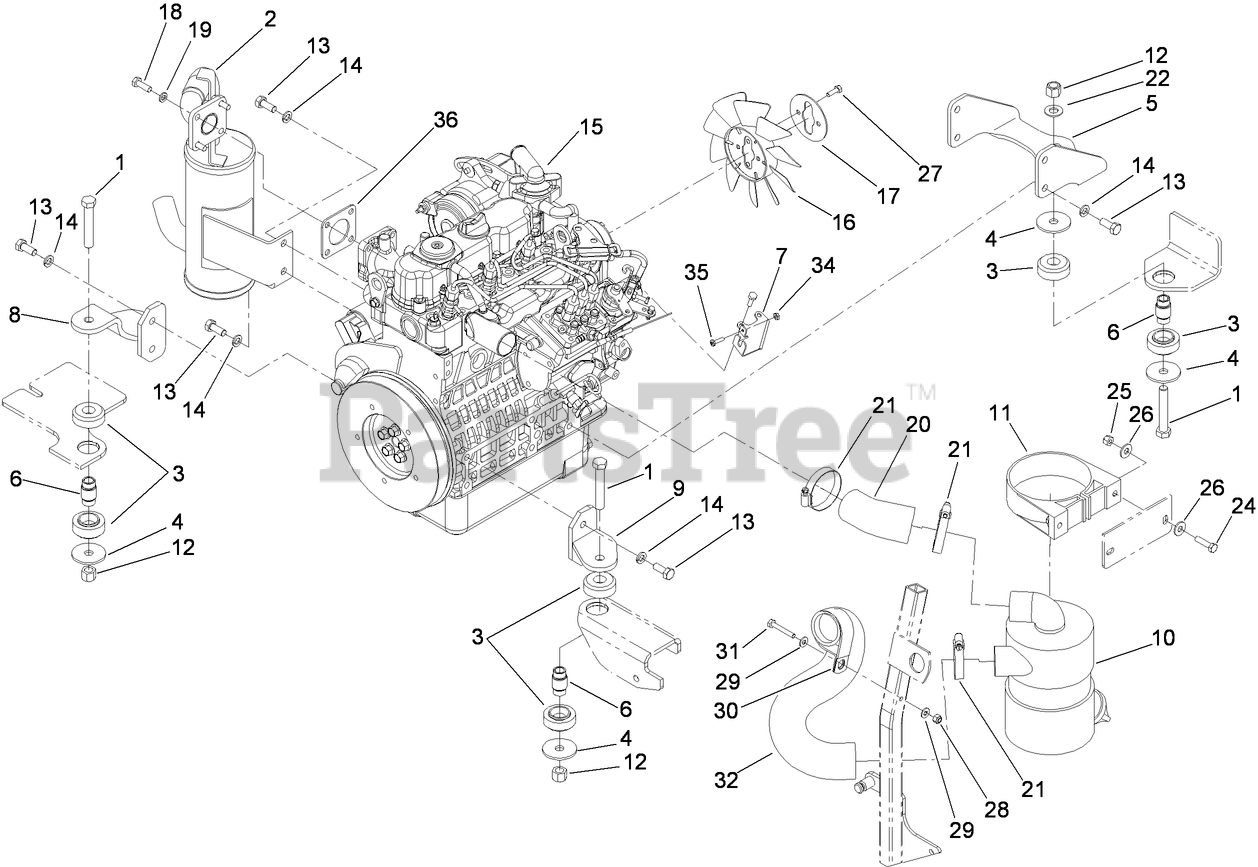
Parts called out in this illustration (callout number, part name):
1	SCREW-HH
2	MUFFLER
3	MOUNT-ISOLATION ASM
4	WASHER-LARGE
5	BRACKET-ENGINE MOUNT, REAR
6	SPACER
7	BRACKET-SUPPORT, THROTTLE
8	SUPPORT-ENGINE, RH
9	SUPPORT-ENGINE, LH
10	AIR CLEANER ASM
11	BRACKET-MOUNTING
12	NUT-LOCK, NI
13	SCREW-HH
14	WASHER-LOCK, SPRING
15	ENGINE-KUBOTA
17	PLATE-REATAINER, FAN
18	SCREW-HH
19	WASHER-LOCK
20	HOSE-INTAKE, AIR CLEANER
21	CLAMP-HOSE
22	WASHER-FLAT
24	SCREW-HH
25	NUT-LOCK, NI
26	WASHER-PLAIN
27	SCREW-HH
28	NUT-LOCK, NI
29	WASHER-FLAT
30	CLIP-LOOM
31	SCREW-HH
32	HOSE-INTAKE, ENGINE
34	NUT-HEX
35	SCREW-TORX
36	GASKET-MUFFLER
